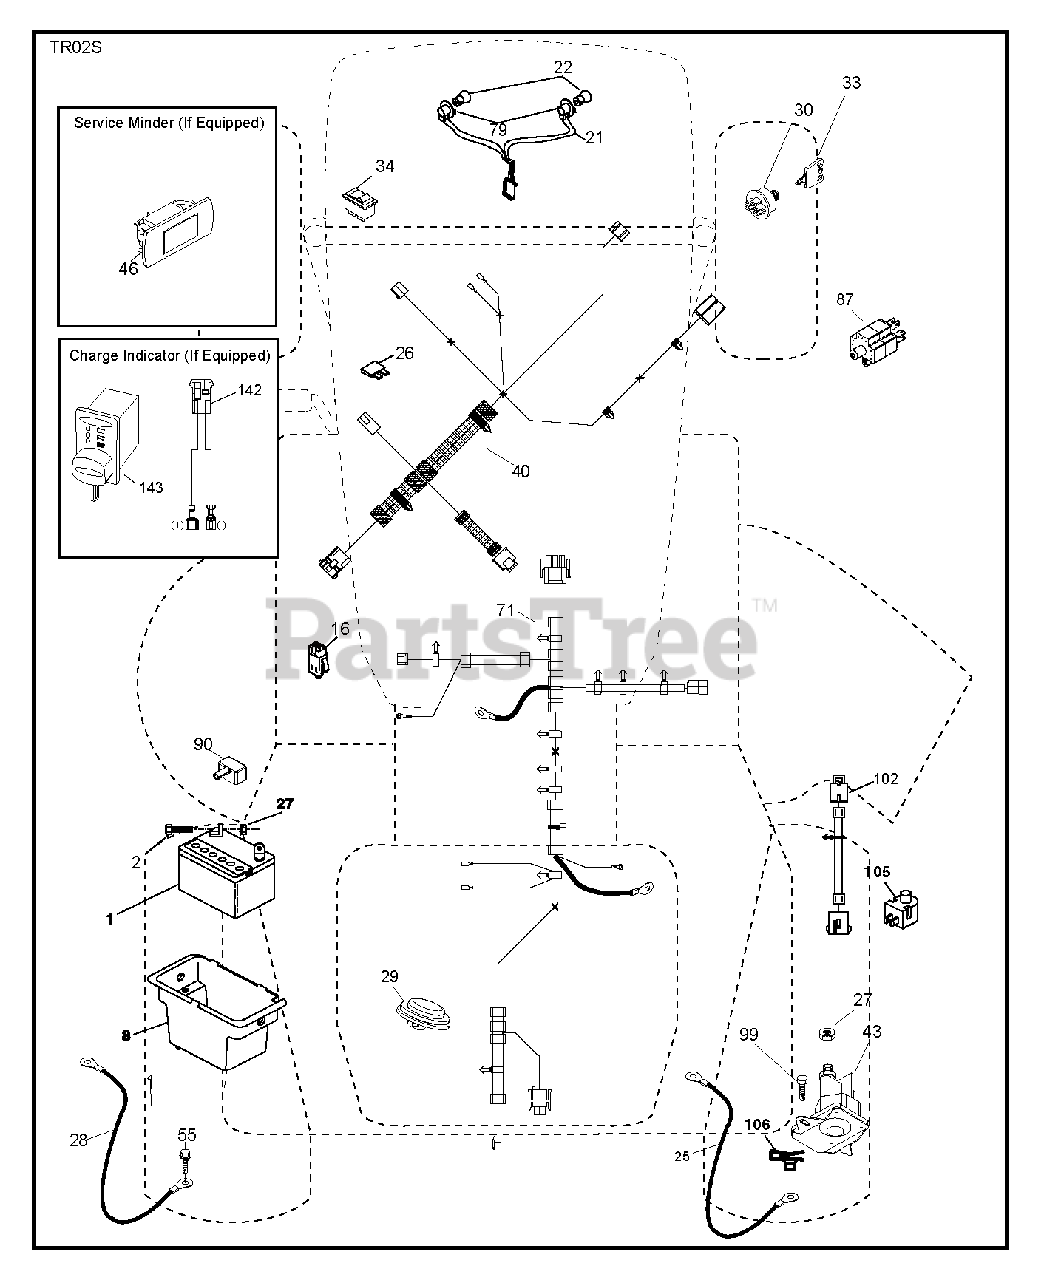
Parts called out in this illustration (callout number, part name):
1	REPL BY 532 12 38-99
2	BOLT.HEX.1/4.X.3/4.DICHROMATE
8	BOX.BATTERY.MNT.REAR.L
16	SWITCH INTERLOOK PUSH-IN
21	HARNESS.LIGHT W/4152J BULBS
22	LIGHTBULB
25	CABLE.BATT.RED.8GA.17
26	FUSE 20AMP
27	NUT
28	CABLE.GROUND.REAR.BATTERY.8G
29	SWITCH.SEAT.DELTA.OPC.
30	SWITCH.IGN.DELTA.W.LGH.ROS
33	KEY.CHAIN.BLISTER.PACK.GEN.USA
34	SWITCH LT
40	HARNESS.TEX.DASH.MAN.REAR BATT
43	SOLENOID.W/BRASS.PLUNGER
55	SCREW 5/16"
71	HARNESS.CHASSIS.RRBATT.RDYSTRT
79	BULB HOLDER ASM.
87	SWITCH.INTRLCK.CLUTCH.
90	COVER.TERMINAL.BATTERY
99	SCREW HEXWSHR 1/4-20X3/4
102	HARNESS.PIGTAIL.VARIATOR.SD
105	REVERSE SWITCH
106	1/4-20 U NUT
